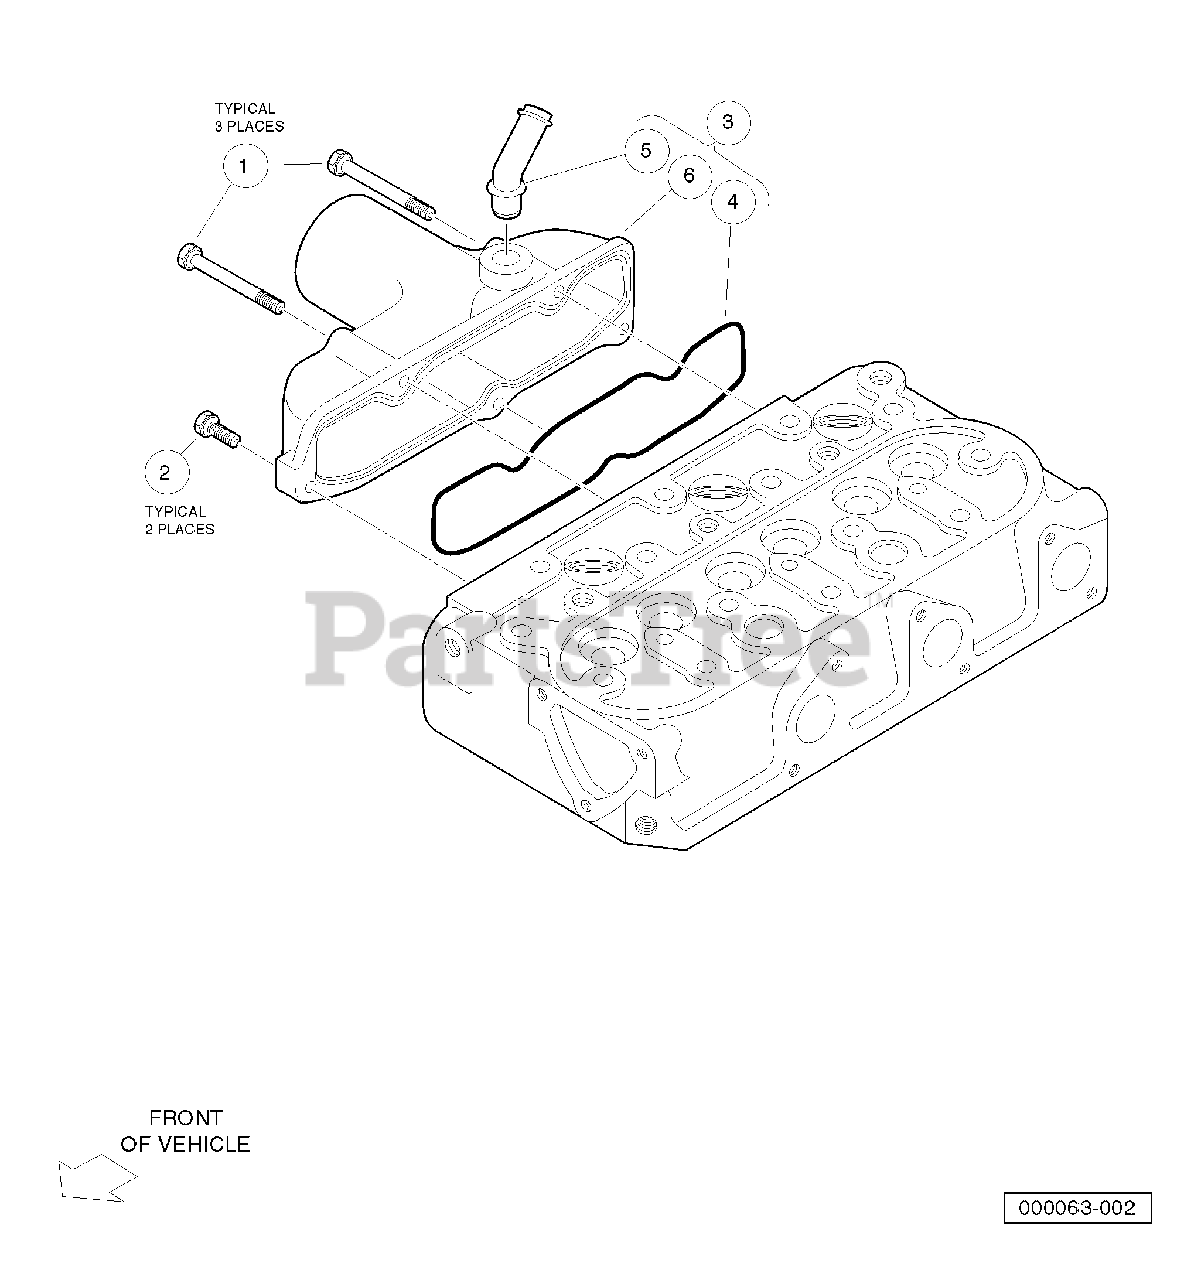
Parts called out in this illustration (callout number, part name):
1	Bolt, M6 X 1 X 45
2	Bolt, D722 Intake Manfld Lower
3	Assembly, Intake Manifold
4	Gasket, Intake Manifold
5	Pipe, Breather
6	Manifold, Intake
